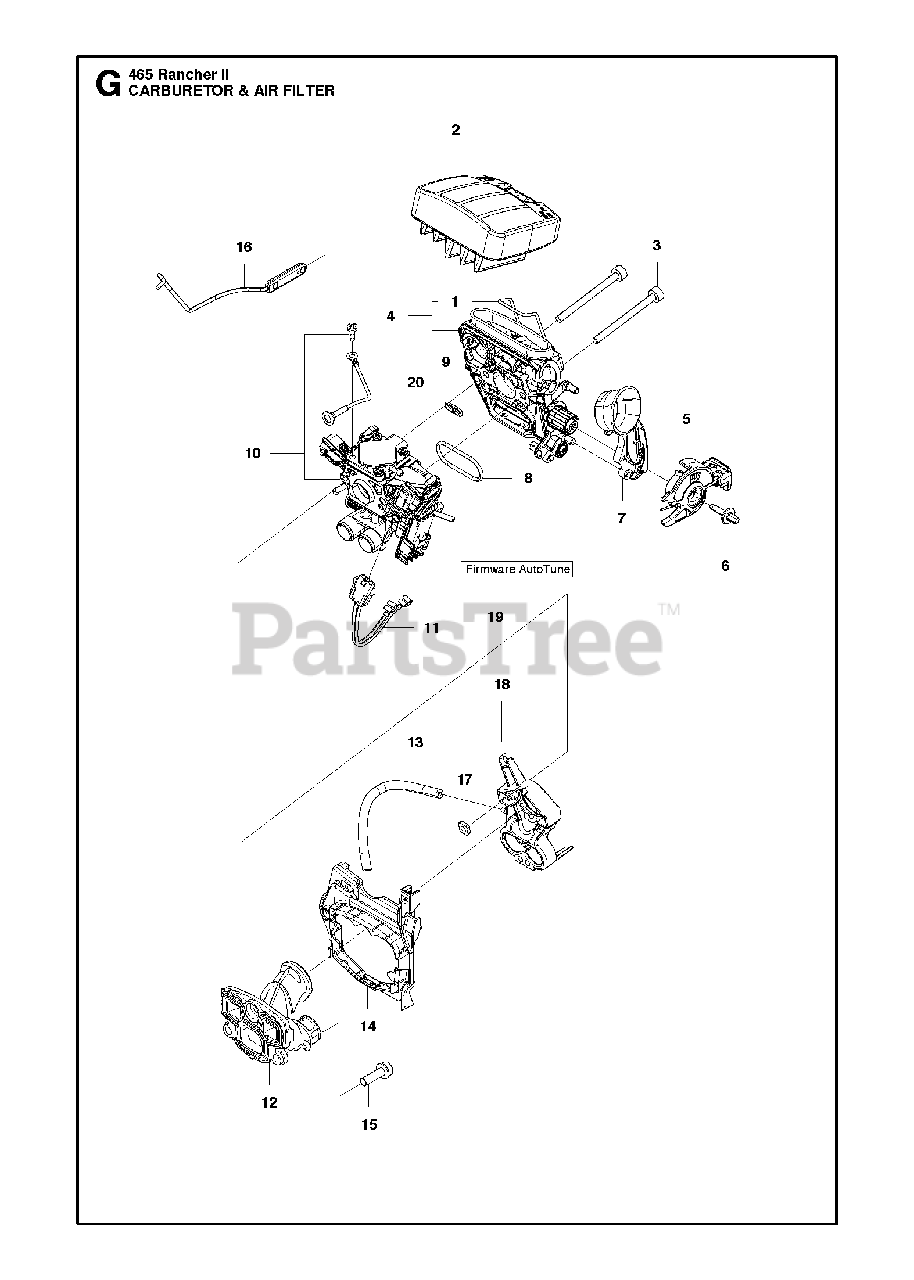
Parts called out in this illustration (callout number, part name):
1	SHACKLE
2	AIR FILTER ASSY
4	FILTER HOLDER ASSY
5	CHOKE CONTROL ASSY CHOKE/STOP
10	CARBURETTOR
11	WIRING ASSY
12	INLET PIPE ASSY
13	HOSE
16	THROTTLE ROD
17	NUT
19	Husqvarna TBD
20	WIRING ASSY
